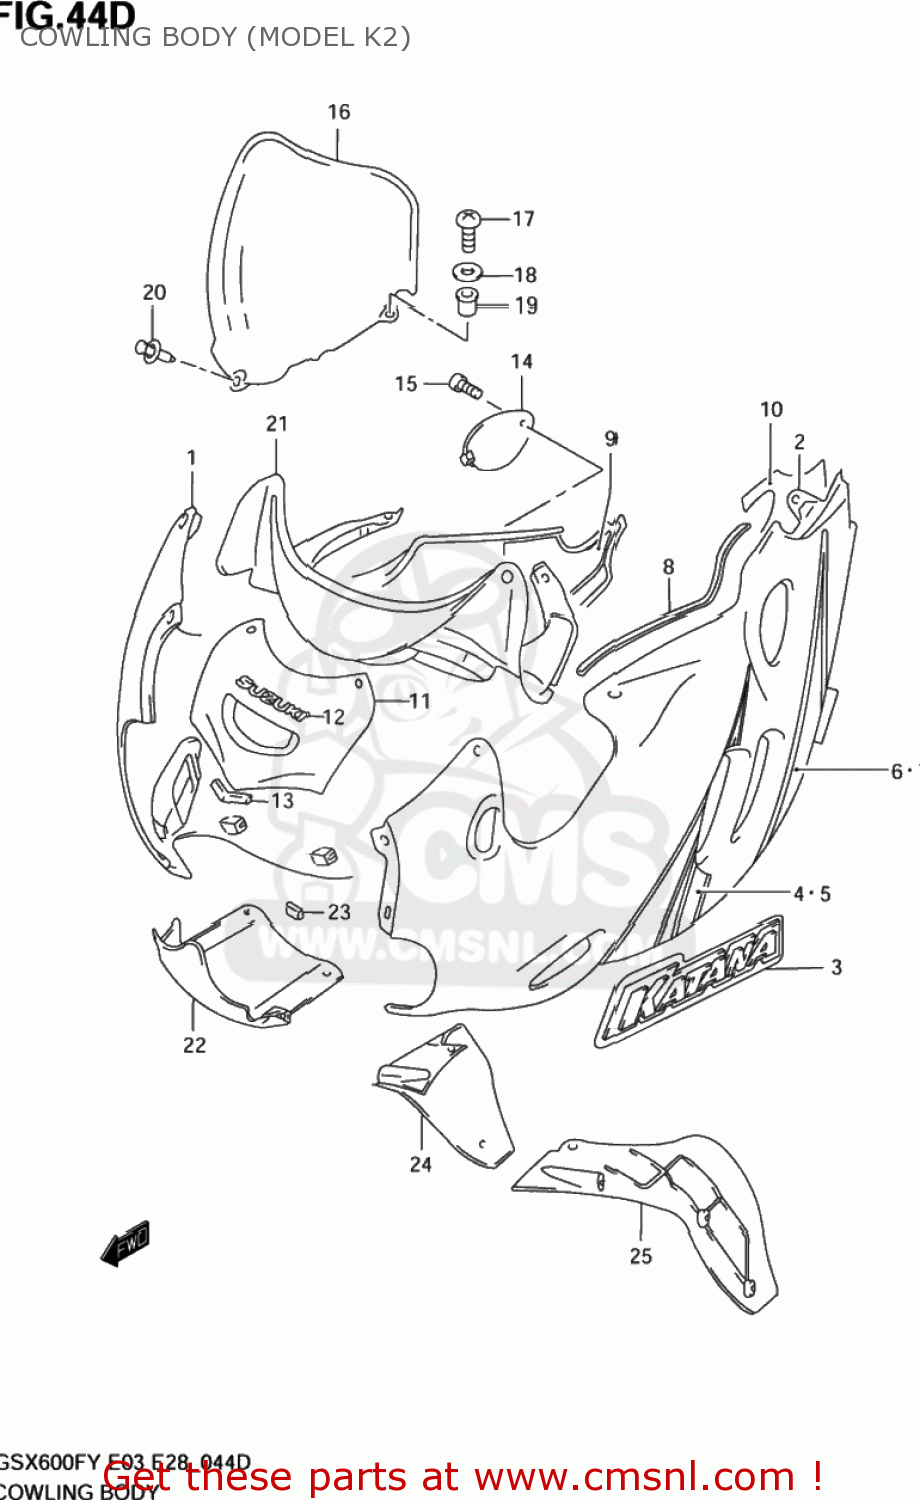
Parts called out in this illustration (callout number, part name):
1	COWLING ASSY,SIDE,R
2	COWLING ASSY,SIDE,L
3	EMBLEM,KATANA
4	TAPE,COWL SIDE,R
5	TAPE,COWL SIDE,R
6	TAPE,COWL SIDE,R
7	TAPE, LOWER LH
8	MOLD,COWLING
9	SHIELD,COWLING COVER,R
10	SHIELD,COWLING COVER,L
11	PANEL,COWLING CTR UPR
12	EMBLEM,SUZUKI
13	CUSHION,CTR PANEL UPR
14	LID,OIL
15	SCREW(6X16)
16	WINDSCREEN
17	SCREW(5X14)
18	WASHER
19	NUT
20	CLIP(BLACK)
21	PANEL,METER
22	PANEL,COWLING CTR LWR
23	CUSHION,CENTER PANEL,LOWER
24	PANEL,COWLING INNER,R
25	PANEL,COWLING INNER,L
